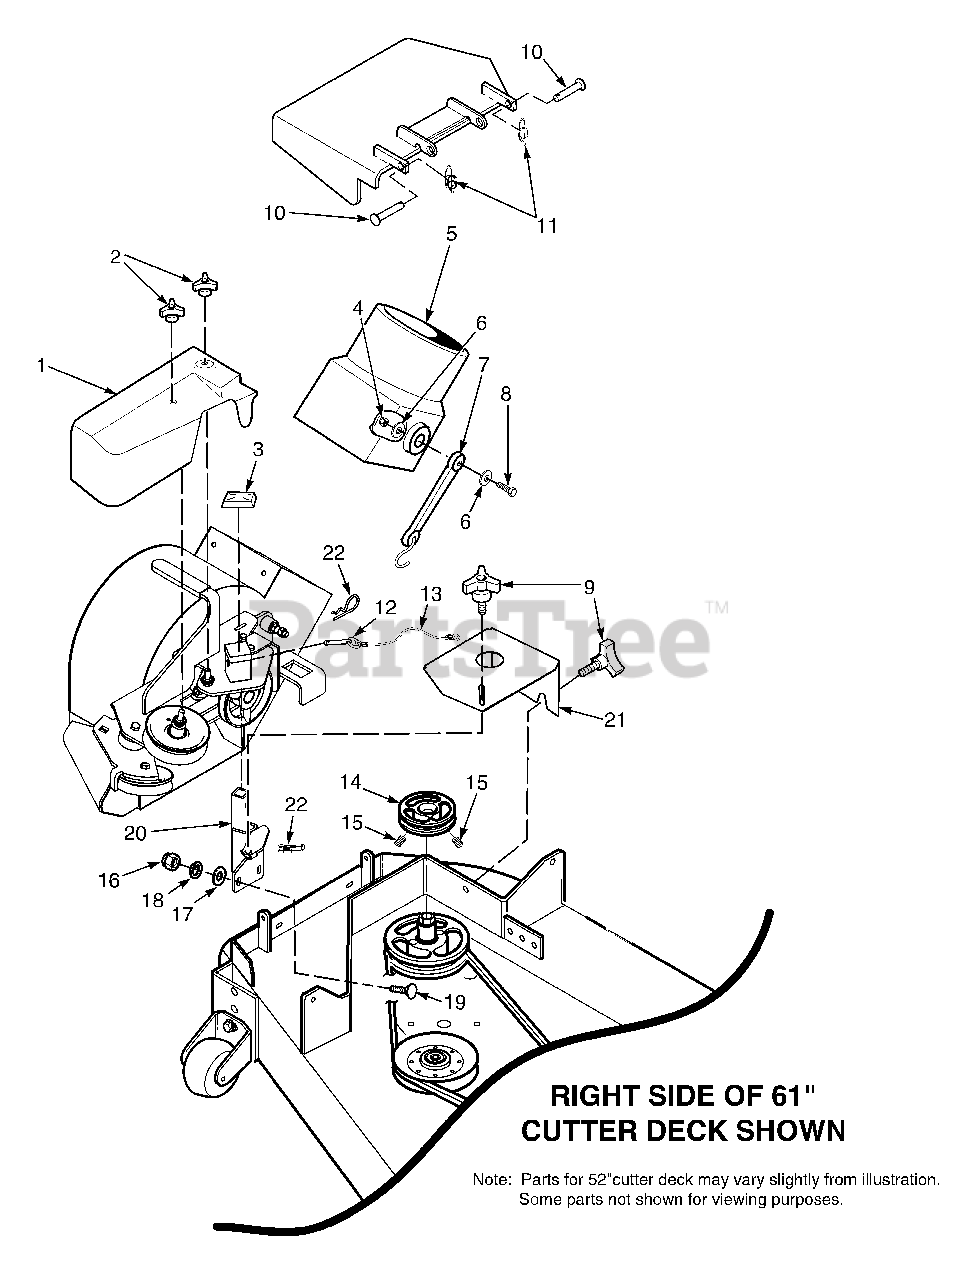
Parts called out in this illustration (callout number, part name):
1	Belt Cover, GC-STWC - 61"
2	Wingnut, Plastic 3/8 Small
3	Cap, Square Vinyl
4	Nut, Elastic Stop 1/4-20
5	Adapter, Blower GC-STT
6	Flatwasher, 1/4-.312 x .750 x .065
7	Rubber Strap 7-3/4"
8	Bolt, Hex Head 1/4-20 x 1-1/4"
9	Knob W/Stud, 3/8-16 x 1-1/4"
10	Clevis Pin, 5/16 x 1-1/2"
11	Pin, Rue Cotter 5/16 Dia.
12	Pin, Ring 1/2 x 2-1/4"
13	Lanyard
14	Pulley, 5-1/2" for 61" Deck
15	Setscrew, 5/16-18 x 3/8"
16	Nut, Elastic Stop 1/2-13
17	Lockwasher, 1/2"
18	Flatwasher, 1/2-.531 x 1.062 x .095
19	Bolt, Hex Head 1/2-13 x 1-1/2" Grade 5
20	Mounting Post Weldment, Blower - 61"
21	Belt Cover, GC-STWC-61
22	Hair Pin Cotter, .177 x 3-1/4"
